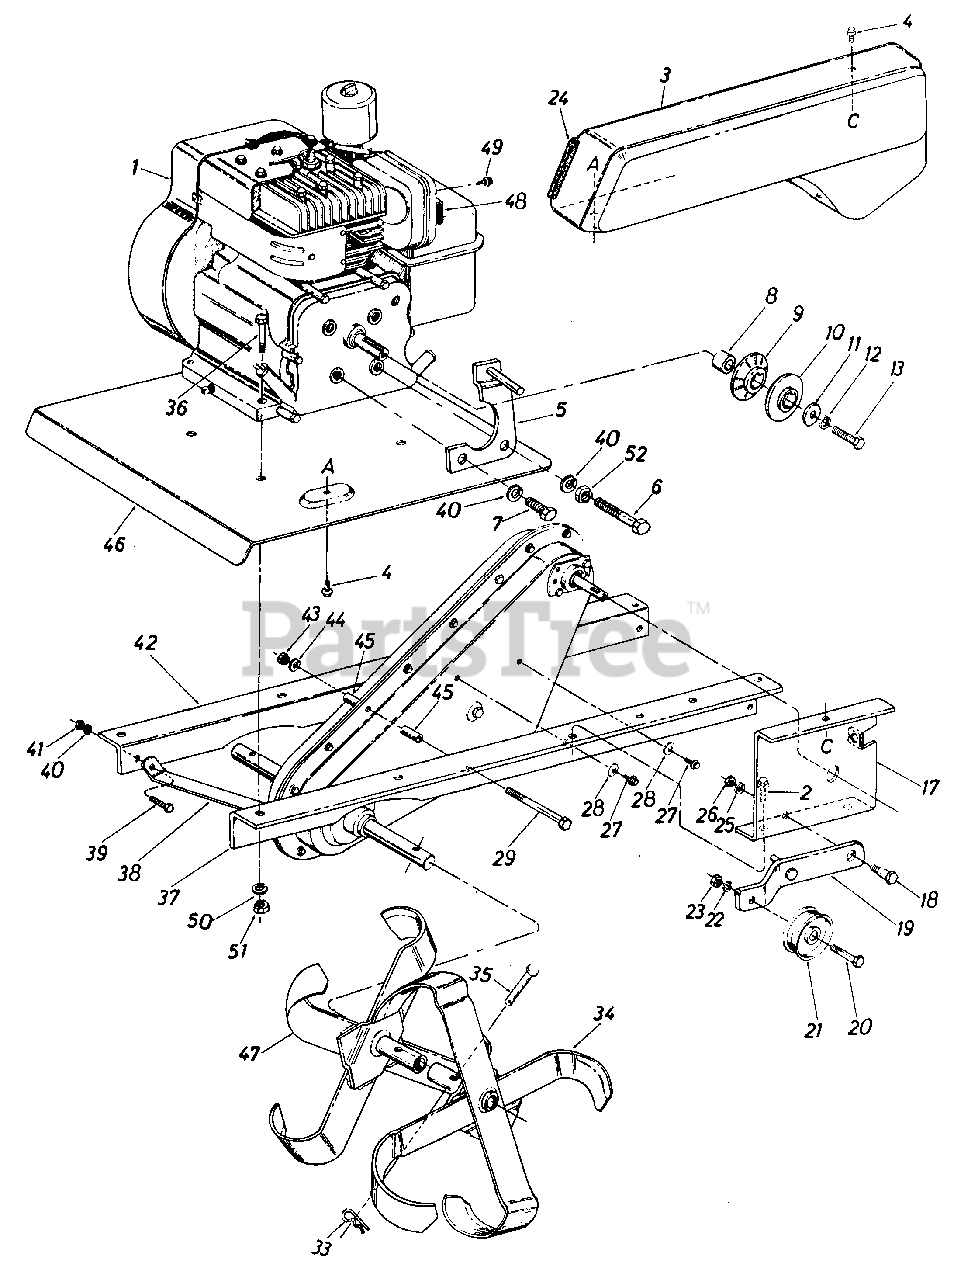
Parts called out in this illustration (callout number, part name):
1	Engine
2	Hex Wash. Hd. Self-Tap Scr. 5/16-24 x .50" Lg.
3	Belt Cover
4	Hex Wash. Hd. Self-Tap Scr.1/4-20 x .50" Lg.
5	Belt Keeper Brkt. Ass'y.
6	Hex Bolt 5/16-24 x 2.25" Lg. (Gr. 5)
7	Hex Bolt 5/16-24 x .62" Lg. (Gr. 5)
11	Fl-Wash. 3/8" I.D. x 1.25" O.D. x .100
12	L-Wash. 3/8" I.D.*
13	Hex Scr. 3/8-24 x 1.00" Lg.
17	Idler Mounting Brkt.
18	Shld. Bolt
19	Idler Bracket Ass'y.
20	Hex Scr. 3/8-16 x 1.50" Lg.
21	Idler Pulley
22	L-Wash. 3/8" I.D.
23	Hex Jam Nut 3/8-16 Thd.
24	Trim Strip-3"
25	L-Wash. 3/8" I.D.
26	Hex Jam Nut 3/8-16 Thd.
27	Hex Wash. Hd. Self-Tap Scr. 1/4-20 x .50" Lg.
28	Belleville Wash. .26 I.D. x .75 O.D. x .060
29	Hex Scr. 5/16-18 x 2.75" Lg.
33	Hairpin Cotter
34	See Tine Chart Below
35	Clevis Pin
36	Bolt 5/16-18 x 1.5" Lg.
37	Frame Rail-L.H.
38	Front Brace Brkt.
39	Hex Scr. 5/16-18 x .75" Lg.
40	L-Wash. 5/16" l.D.
41	Hex Cent. L-Nut 5/16-18 Thd.
42	Frame Rail-R.H.
43	Hex Cent. L-Nut 5/16-18 Thd.
44	L-Wash. 5/16" I.D.
47	See Tine Chart Below
48	Deflector
49	Hex Self-Tap Scr. #8-32 x .38n Lg.
50	L-Wash. 5/16" I.D.
51	Hex Nut 5/16-18 Thd.
52	Hex Nut 5/16-24 Thd.
